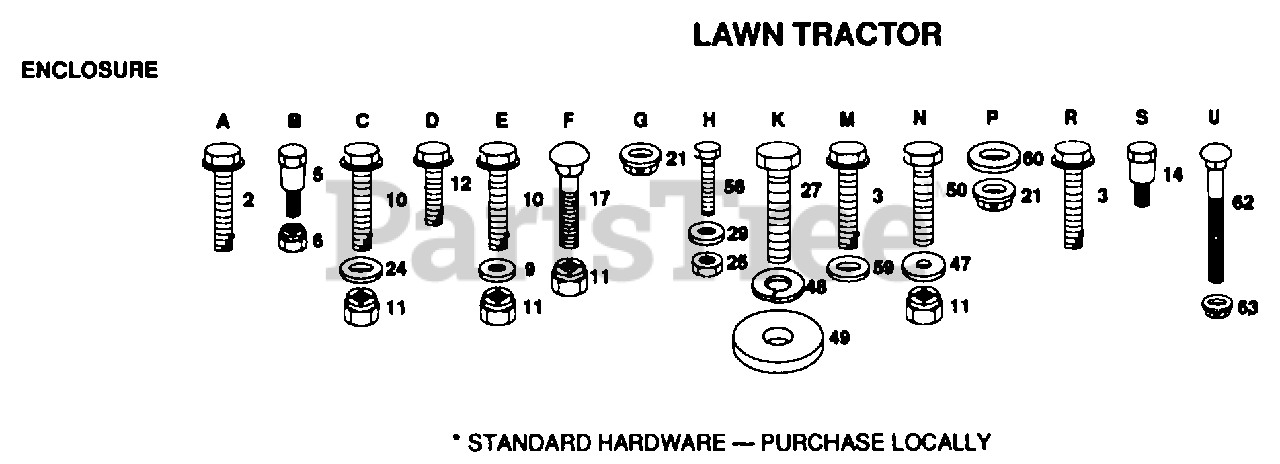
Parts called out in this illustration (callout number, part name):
2	SCREW
3	SCREW GTV
9	WASHER
12	SCREW LT
17	BOLT
21	PAL NUT LT
24	WASHER
25	NUT
27	BOLT
47	WASHER
48	LOCKWASHER
49	WASHER
50	BOLT
56	SCREW SPECIAL
59	WASHER
60	WASHER PM
62	BOLT
